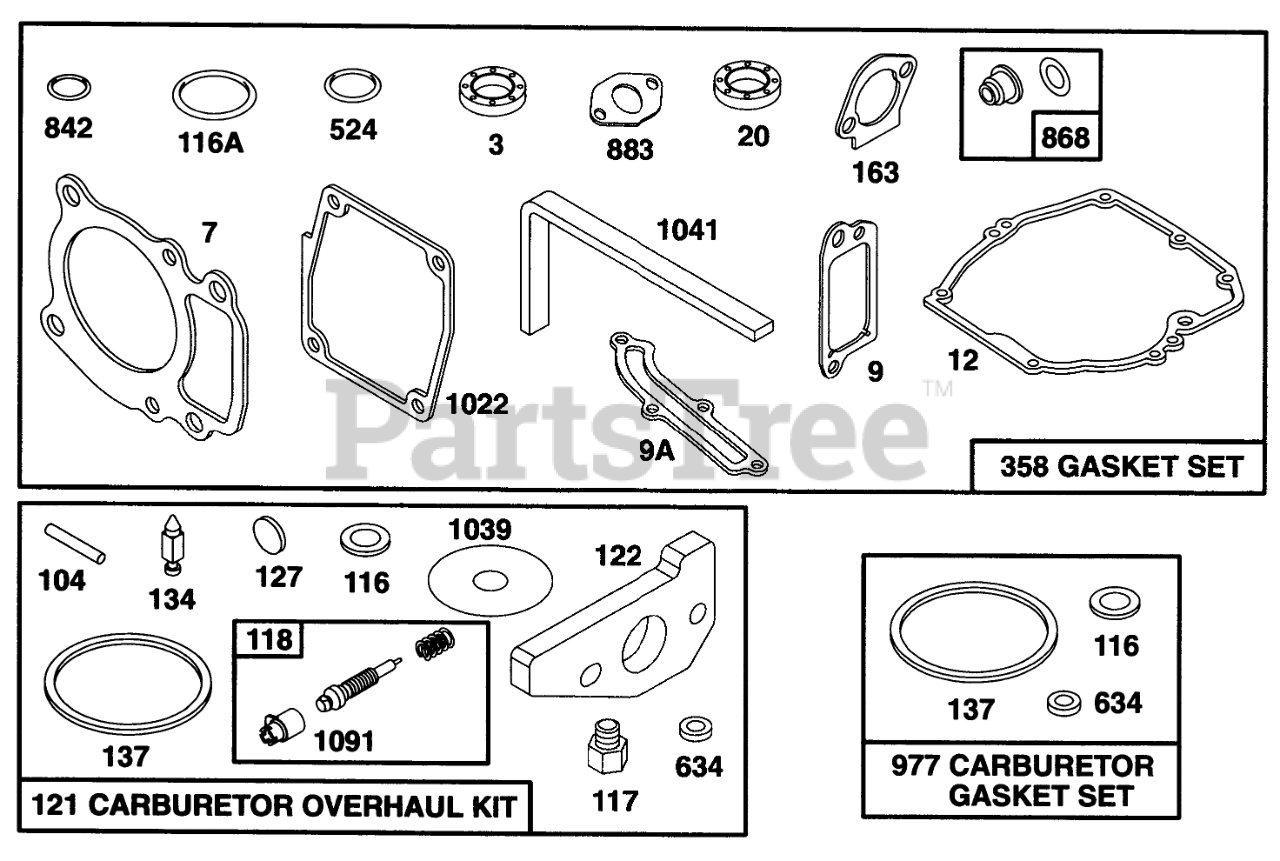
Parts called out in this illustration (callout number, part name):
3	SEAL - OIL
7	CYLINDER HEAD GASKET
9	BREATHER GASKET
9A	GASKET-BREATHER
12	ENGINE BASE GASKET
20	SEAL-OIL
104	FLOAT HINGE PIN
116	SEALING GASKET
116A	O RING SEAL
117	Jet-Main
118	VALVE/SPRING - NEEDLE
121	KIT-CARBURETOR OVERHAUL
122	ADAPTER ASSEMBLY
127	PLUG - WELCH
134	Valve-lnlet (Includes Seat)
137	FLOAT BOWL GASKET
163	AIR CLEANER GASKET
358	CYLINDER HEAD
524	O-RING
634	SEAL WASHER
842	O-RING
868	ASM - VALVE SEAL
883	EXHAUST GASKET
977	CARBURATOR GASKET SET
1022	ROCKER COVER GASKET
1039	FLOAT LIMITER
1041	SEAL - FOAM
1091	CAP - LIMITER
